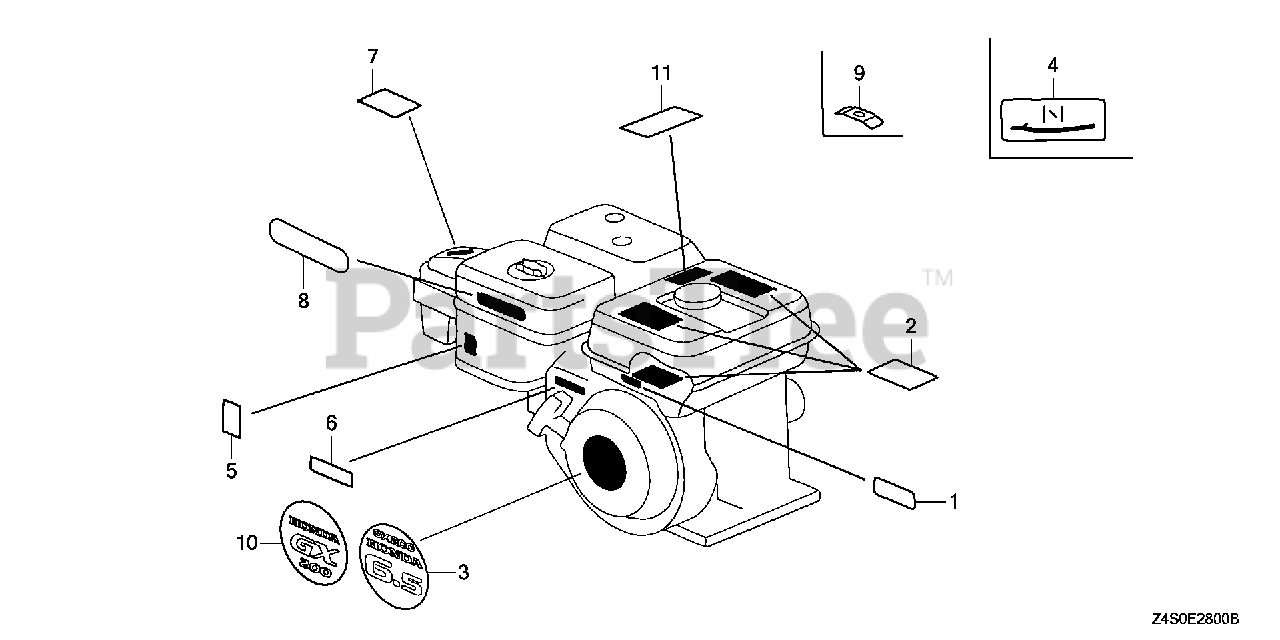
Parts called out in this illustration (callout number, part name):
1	LABEL, E-SPEC (15.5X27.5)
2	MARK, OPERATOR CAUTION (ENGLISH)(MADE IN JAPAN)
2	MARK, OPERATOR CAUTION (PICTOGRAPH)(MADE IN JAPAN)
3	EMBLEM (GX200)
5	MARK, CHOKE (GRAY)
6	MARK, THROTTLE INDICATION
10	EMBLEM (GX200)
